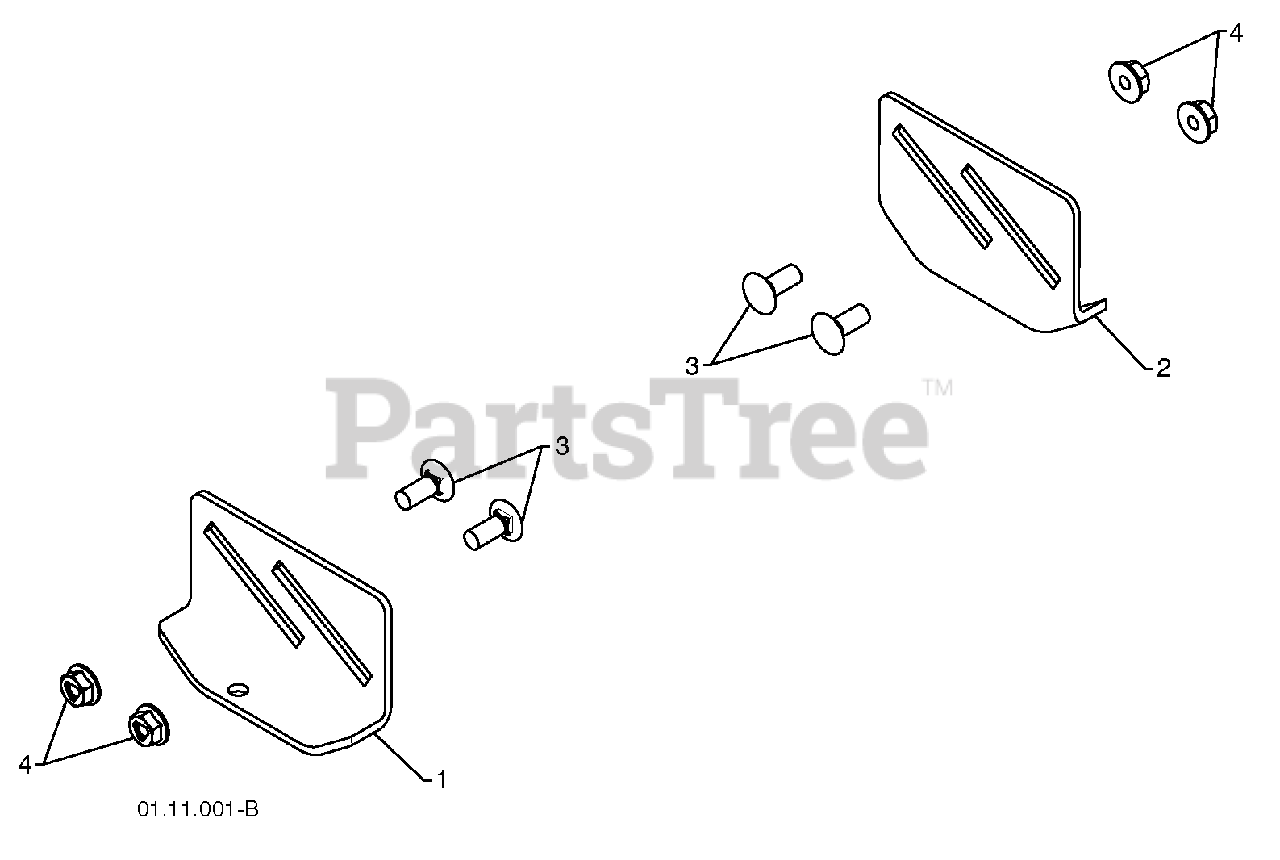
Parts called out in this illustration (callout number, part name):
1	SKID PLATE LH
2	SKID PLATE RH
3	CARRIAGE BOLT 5/16-18 X .75
4	NUT 5/16-18
